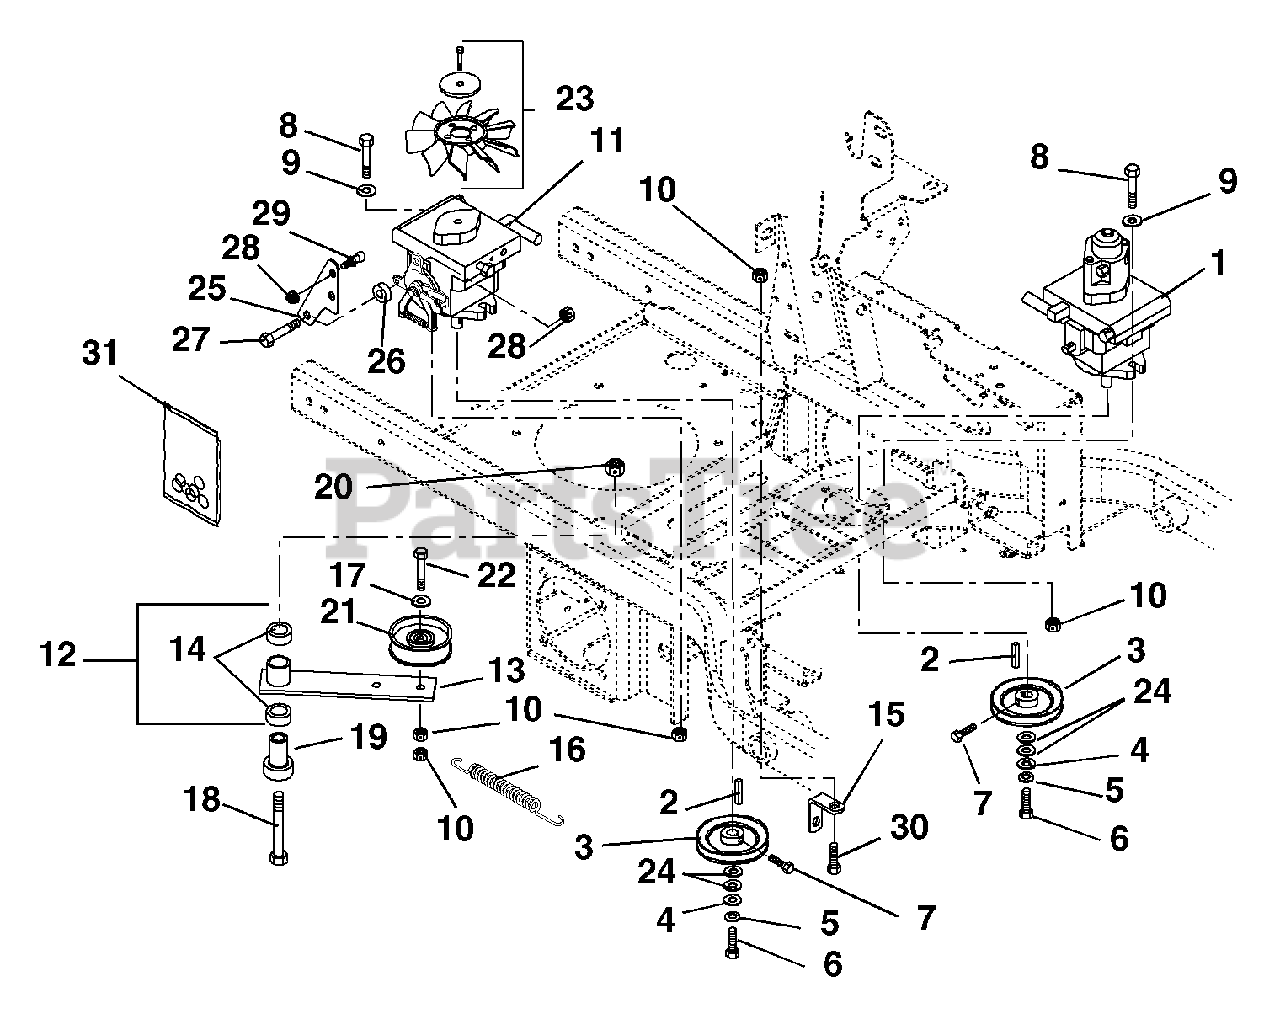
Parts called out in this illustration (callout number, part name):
1	Hydrostat BDP with Auxiliary
2	Key-Straight 5mm x 25mm x 5mm
3	Sheave 4.0 x .199
4	Washer-Flat-Steel .281 x 1.00 x .063
5	Washer-Locking .25 x .062
6	Bolt-Hex M6 x 1.0 x 12
7	Bolt-Hex .25-20 x .50 Grade 5
8	Bolt-Hex .38-16 x 1.25 Grade 5
9	Washer-Flat-Steel .39 x .75 x .125
10	Nut-Locking-Top-Flange .38-16
12	Assembly,Idler Arm Guard Drive
13	Weldment, Idler Arm Ground Drive
14	Bearing, 1.00 x 1.12 x .75
15	Anchor-Spring-Idler
16	Spring-Tension .120 x .845 x 6.500
17	Washer-Flat-Steel .39 x.75 x.125
18	Bolt-Hex .50-13 x 3.50 Grade 5
19	Bearing, Pedestal Powdered Metal
20	Nut-Locking-Top-Flange .50-13
21	Idler, Flat 4.00 x 1.06
22	Bolt-Hex .38-16 x 2.25 Grade 5
23	Fan, Cooling
24	Washer-Flat-Steel .656 x 1.31 x .095
25	Bracket, Return to Neutral/Damper
26	Spacer .344 x 1.00 x .375
27	Bolt-Hex .31-18 x 1.25 Grade 5
28	Nut-Locking-Top-Flange .31-18
29	Stud- Ball
30	Bolt-Hex .38-16 x .75 Grade 5
31	Kit, Pump Seal (BDP-10A)
